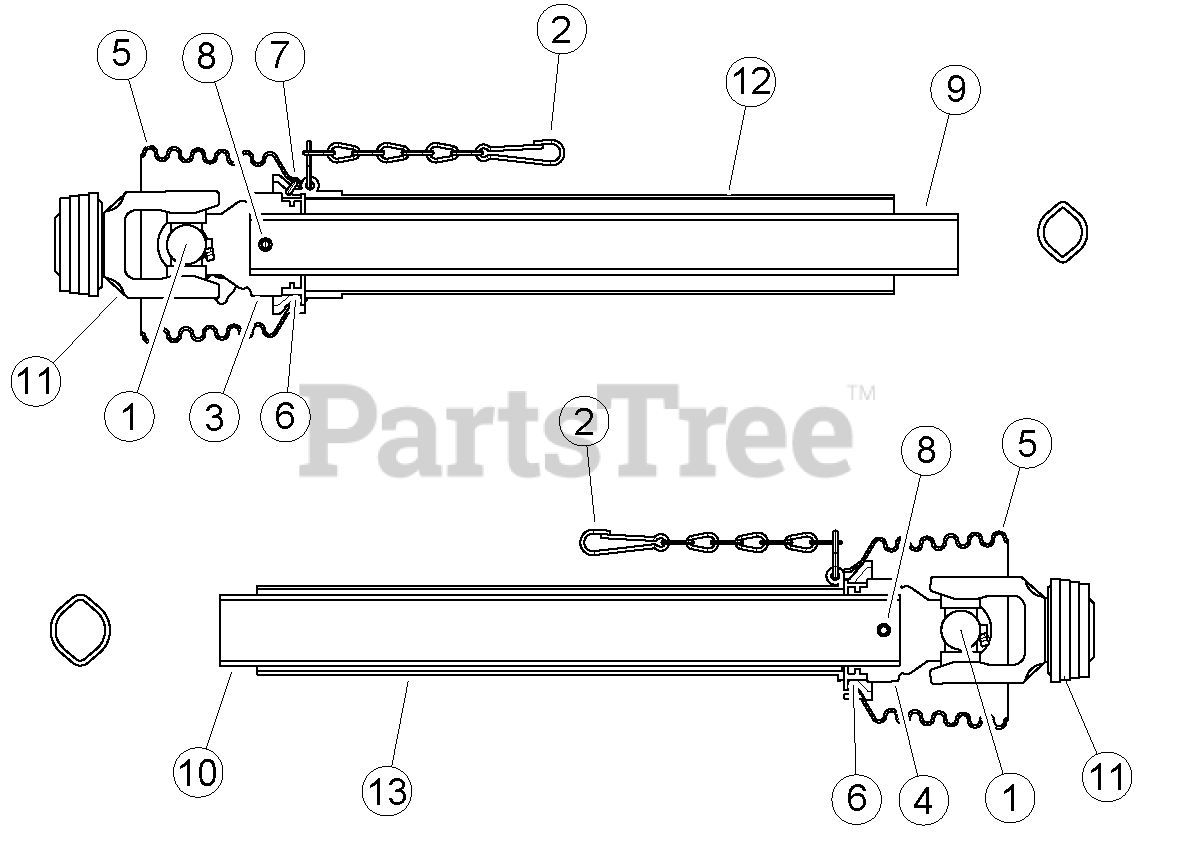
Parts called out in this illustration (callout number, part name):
1	KIT, CROSS & BEARING W-2400
2	CHAIN, SAFETY
3	YOKE, INBOARD 1B
4	YOKE, INBOARD 2A
5	CONE, 6 RIB SAFETY
6	RING, SC25 BEARING
7	SCREW, WS365305
8	PIN, M10 X 80 SPRING
9	PROFILE, INNER 1B
10	PROFILE, OUTER 2A
11	YOKE, 1-3/8-6 SPLINGE ASGE
12	GUARD, TUBE OUTER
13	GUARD, TUBE INNER
